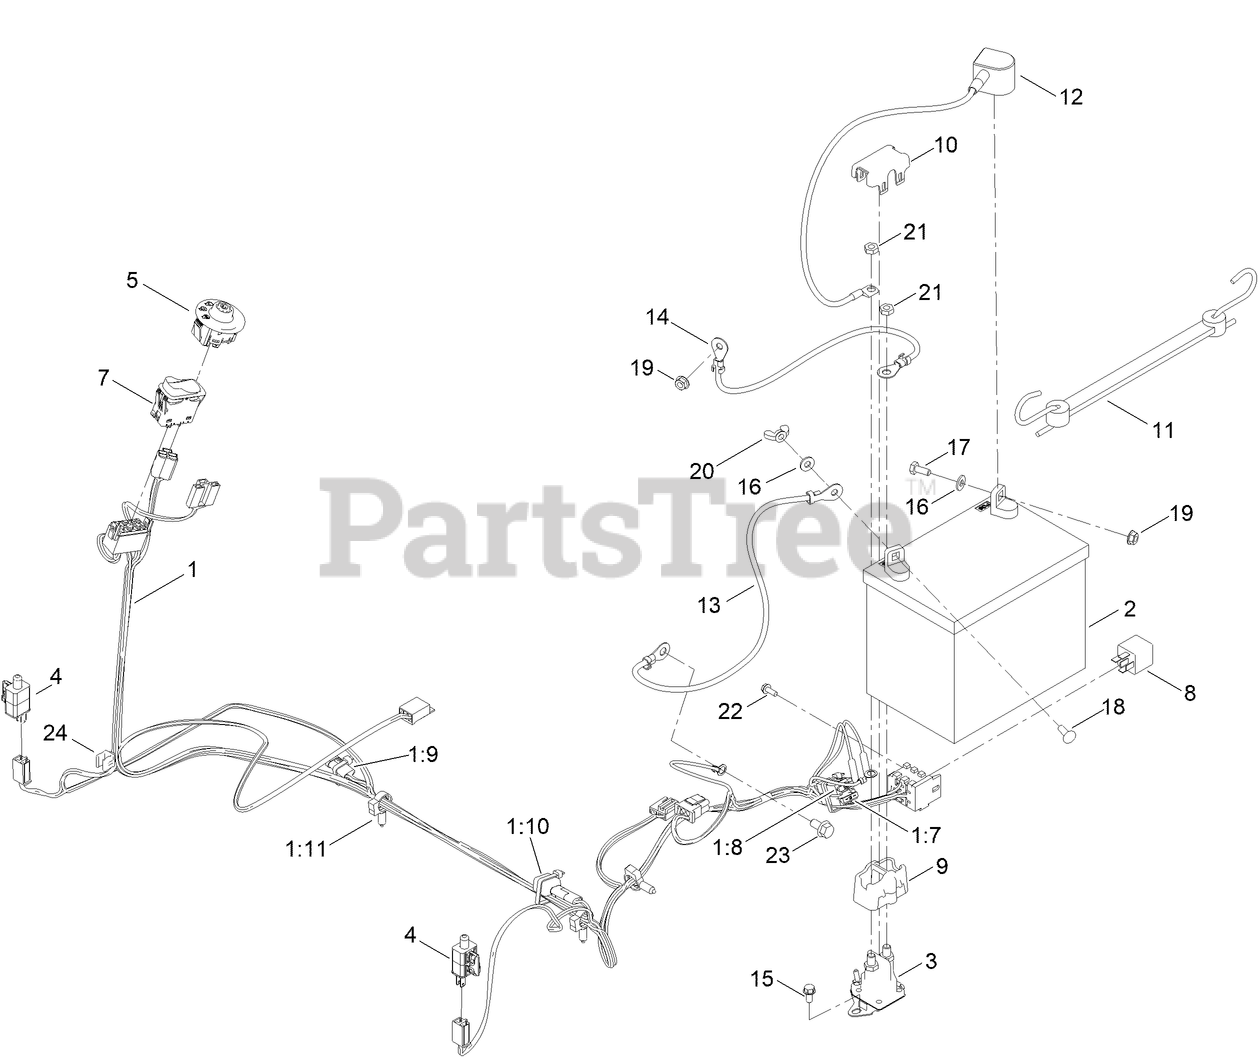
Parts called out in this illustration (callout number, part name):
1	HARNESS-WIRE, MAIN
1:7	FUSE-BLADE, 15 AMP
1:8	FUSE-BLADE, 25 AMP
1:9	CONNECTOR-MOLDED, 1F,1M
1:11	CLIP-TUBING, HARNESS
3	SOLENOID
4	SWITCH
5	SWITCH-IGNITION
7	SWITCH-ROCKER, ON-NONE-ON
9	COVER-SOLENOID
10	CAP-SOLENOID
11	HOLDDOWN-BATTERY
12	CABLE-BATTERY,RED
13	CABLE-BATTERY, BLACK
14	CABLE-BATTERY, POSITIVE
15	SCREW-HWH
16	WASHER-FLAT
17	SCREW-HH
18	BOLT-CARR
19	NUT-HF
20	NUT-WING
21	NUT-JAM
22	SCREW-TAPTITE
23	SCREW-HHF
24	CLIP-EDGE W/TIE, PERPENDICULAR
